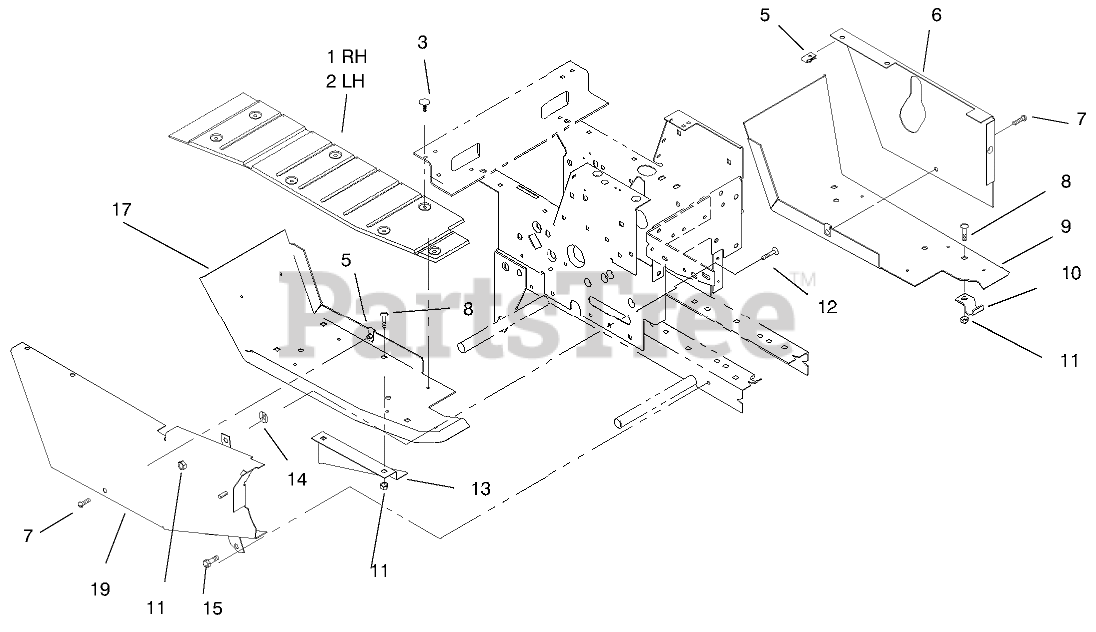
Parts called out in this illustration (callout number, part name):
1	PAD-FOOT RH
2	PAD-FOOT LH
3	FASTENER-PANEL
6	COVER-LH
7	SCREW-PPH
8	BOLT-CARR
9	FOOTREST-LH
10	BRACKET
11	NUT-LOCK, NI
12	BOLT-CARR
13	GUIDE-LOWER BELT
14	NUT-PUSH
15	Bolt
17	FOOTREST-RH
19	SINGLE BELT GUARD ASM
